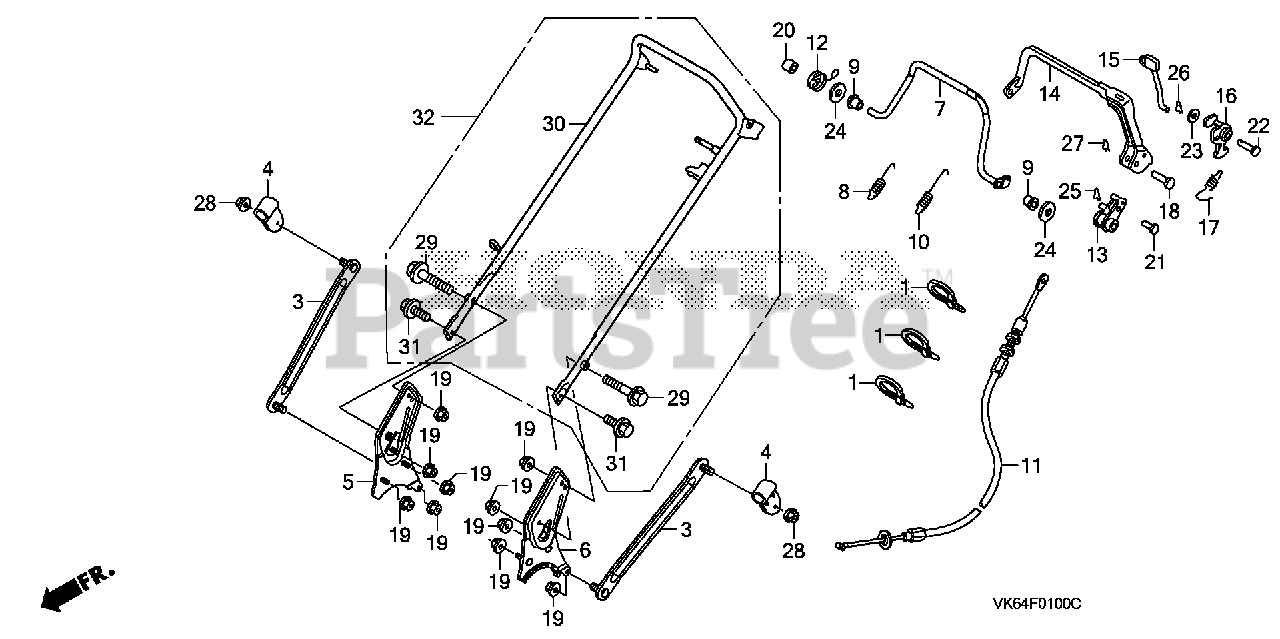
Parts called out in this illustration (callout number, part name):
1	TIE, CABLE
3	PLATE, HANDLE SUPPORT
4	HANGER, HANDLE SUPPORT
5	STAY, R. HANDLE
6	STAY, L. HANDLE
7	LEVER, CLUTCH
8	SPRING, CLUTCH
9	BUSH, CLUTCH LEVER
10	SPRING, CLUTCH LEVER RETURN
11	CABLE, ROTO-STOP
12	SPRING, R. STOP RETURN
13	ARM, ROTO-STOP CABLE
14	LEVER, ROTO-STOP
14	LEVER, ROTO-STOP (FOR U.S.A.)(COO)
15	ROD, RATCHET PUSH
16	LEVER, LOCK
17	SPRING, RATCHET RETURN
18	PIN, CLUTCH LEVER
19	NUT, SELF-LOCK (8MM) (CLINCH)
20	COLLAR (8X11X13.5)
21	PIN, CABLE JOINT
22	PIN, LOCK LEVER HINGE (6X30)
23	WASHER, PLAIN (6MM)
24	WASHER, PLAIN (8MM)
25	PIN, SPLIT (1.6X12)
26	PIN, LOCK (6MM)
27	PIN, LOCK (8MM)
28	NUT, SELF-LOCK (8MM) (CLINCH)
29	BOLT, FLANGE (8X40)
30	PIPE, HANDLE *NH105* (MAT BLACK)
31	BOLT, FLANGE (8X16)
